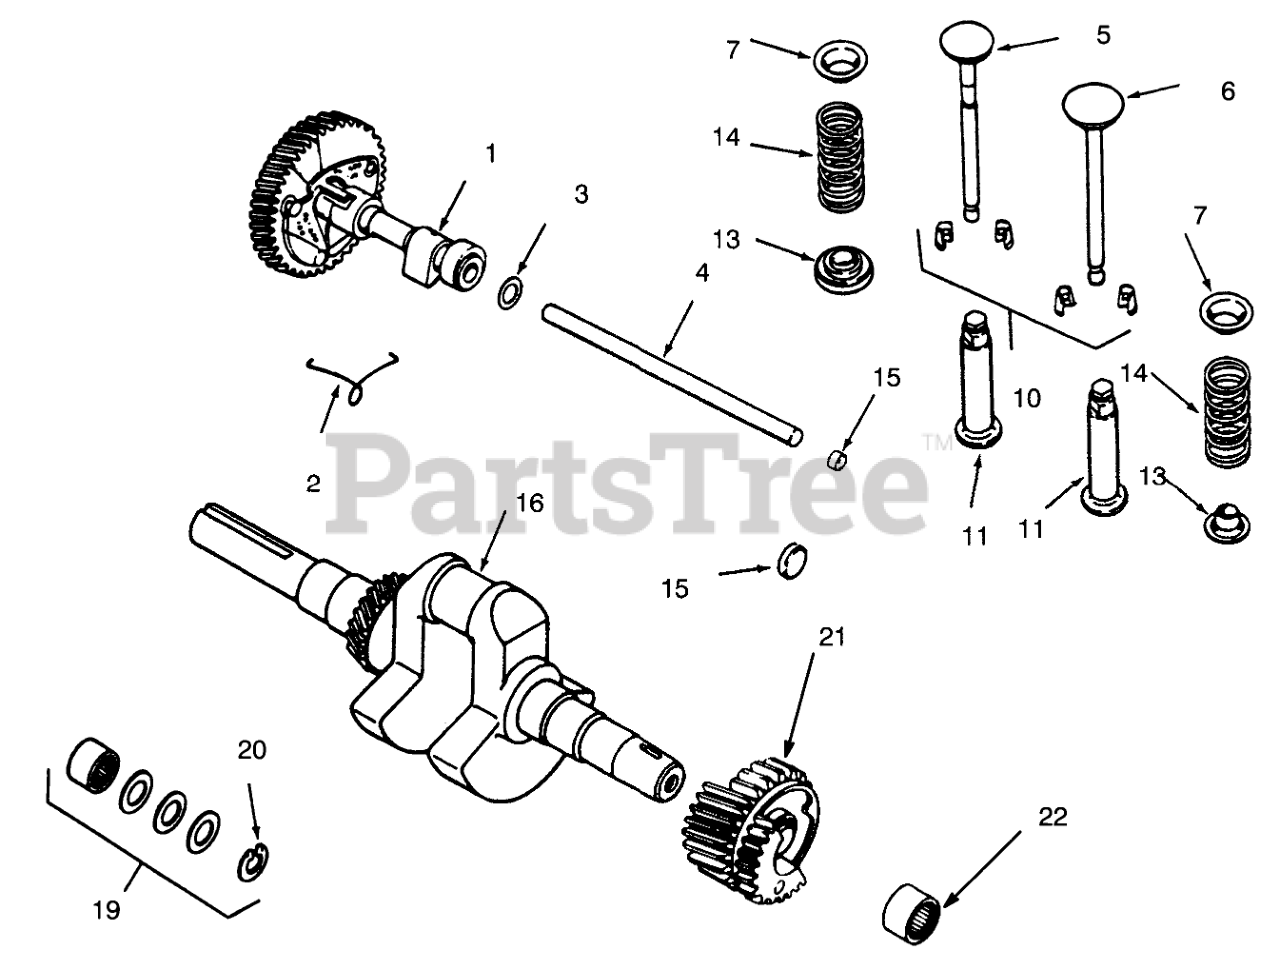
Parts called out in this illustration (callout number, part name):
1	Camshaft Assy (Incl. Ref.# 2)
2	Spring
3	Spacer .005
4	Camshaft Pin
5	Valve-Exhaust
6	Valve-Intake
7	UpperSpring Retainer
10	Kit-Retainer
11	Tappet
13	Rotator-Valve
14	Spring
16	Kit-Crankshaft (Includes Flywheel Hdwr.)
19	Kit-Spacer (Incl. Ref.#20)
20	Retainer
21	Gear Assembly (Incl. Ref. #22)
22	Bearing-Needle
